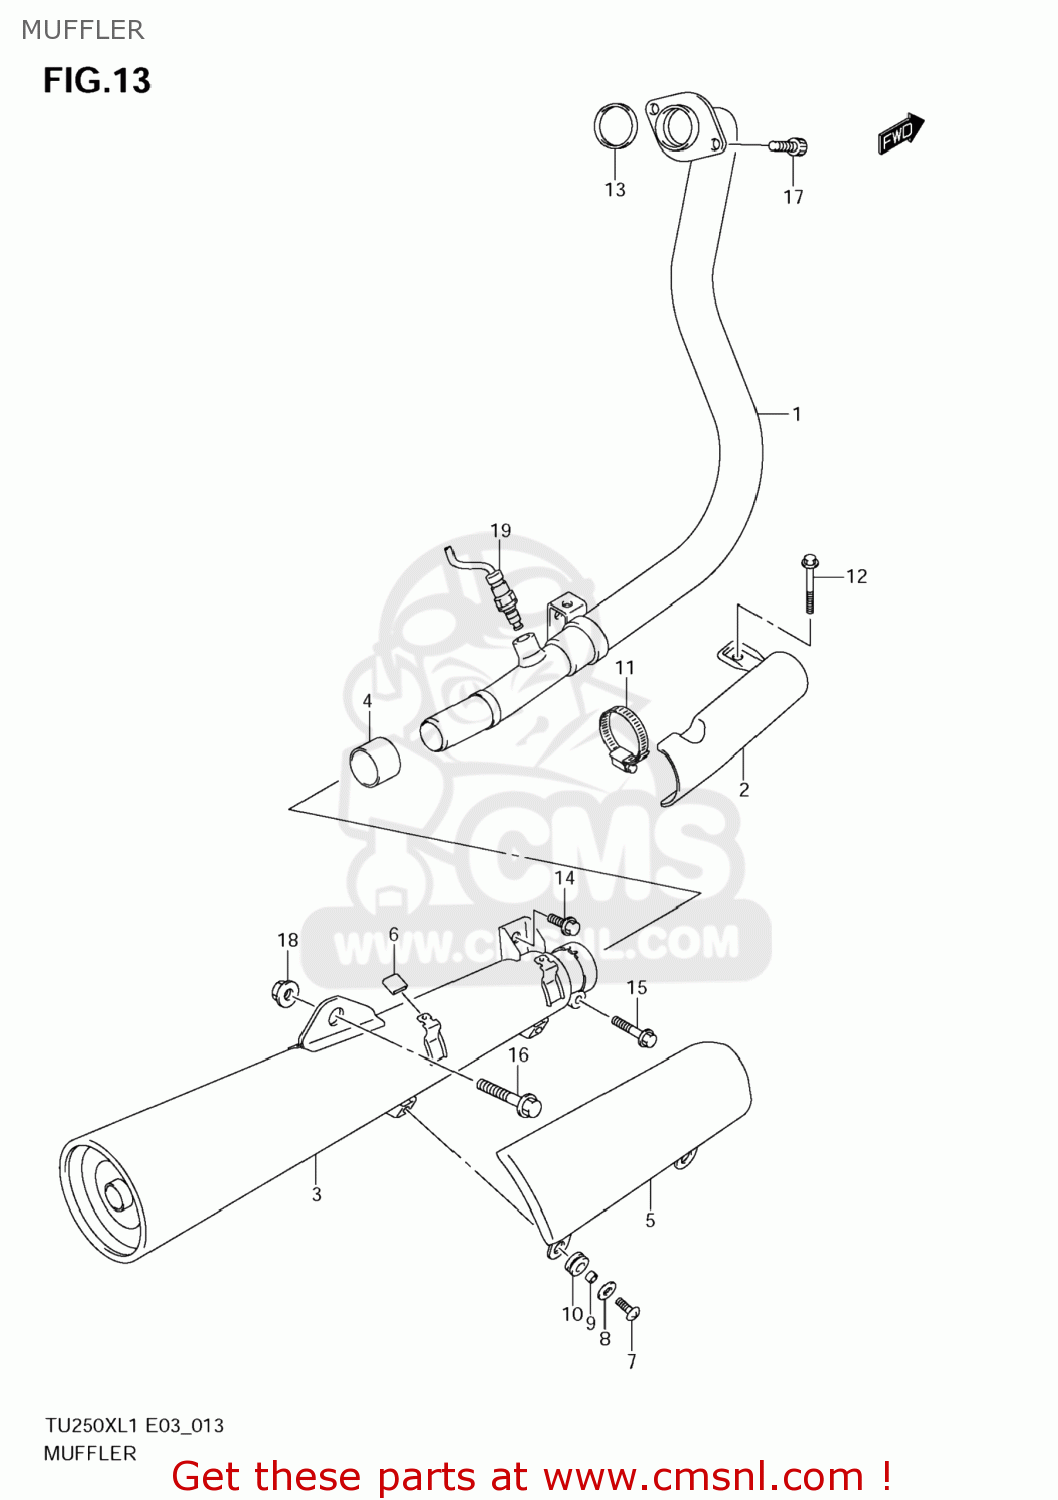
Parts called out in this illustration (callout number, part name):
1	PIPE,EXHAUST
2	COVER,EXHAUST PIPE
3	BODY,MUFFLER
4	CONNECTOR,MUFFLER
5	COVER,MUFFLER
6	GROMMET
7	SCREW(6X16)
8	WASHER(6.5X18X1)
9	SPACER(6.5X9X5)
10	CUSHION
11	CLAMP
12	BOLT
13	GASKET,EXHAUST PIPE (NAS)
14	BOLT(8X20)
15	BOLT
16	BOLT
17	BOLT
18	NUT
19	SENSOR,OXYGEN
